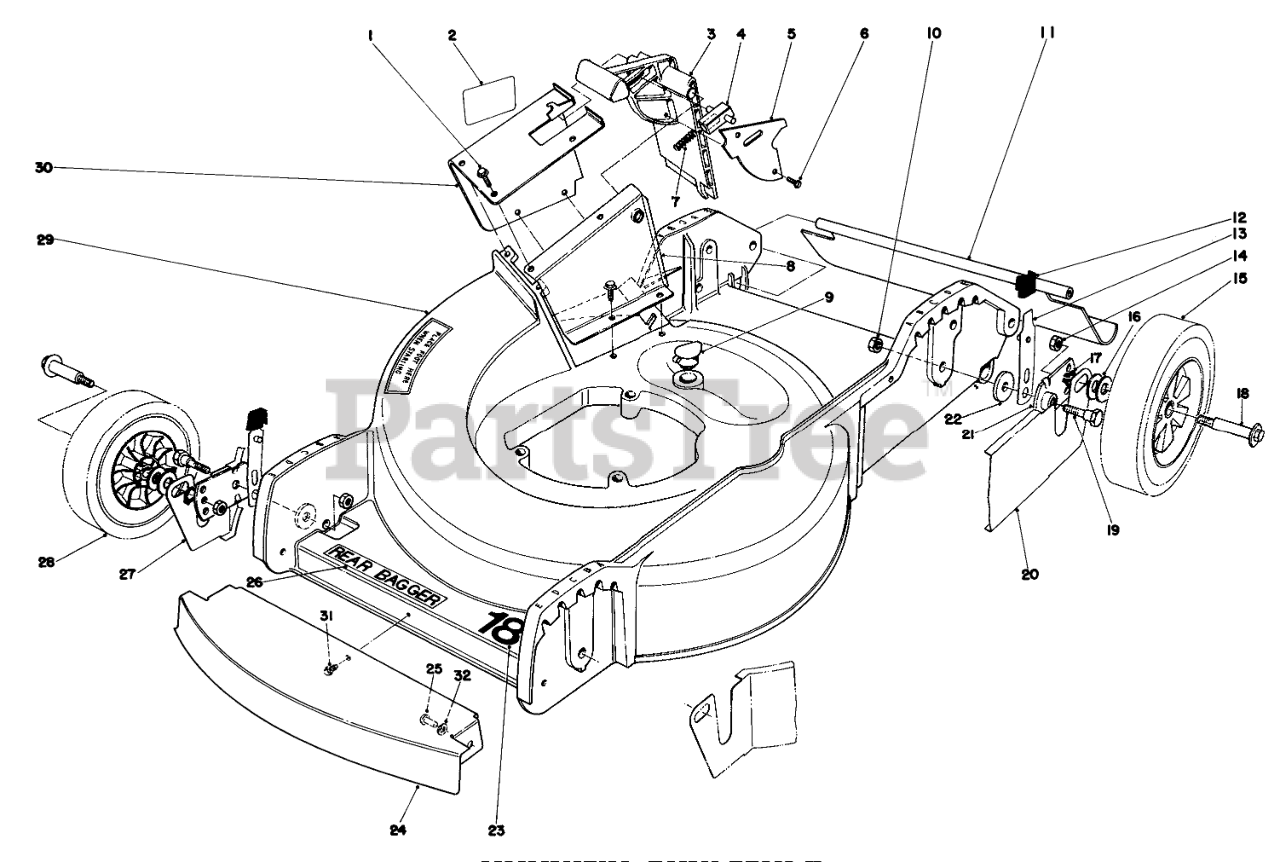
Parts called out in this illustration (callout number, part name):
1	SCREW
2	Decal-Caution
3	Door Mulching
4	Door Latch
5	Cover Door
7	SPRING-COMPRESSION, LATCH
8	Inner Tunnel
9	WASHOUT PLUG
10	Nut
11	SHIELD - TRAILING
12	KNOB-ARM
13	SPRING ARM ASM
14	Nut
15	Wheel Assembly
16	WASHER-FLAT
17	Grip Ring
18	WHEEL BOLT
19	PIVOT SCREW
20	Shield Left
21	PIVOT ARM ASSY
22	PIVOT WASHER
23	Decal
24	Shield Front
25	POP RIVET 3/16X.375LG
26	DECK DECAL
27	Shield Right
28	Wheel Assembly
29	Housing
30	Tunnel Outer
31	SCREW-HWHTF
32	WASHER CONTROL PIVOT
